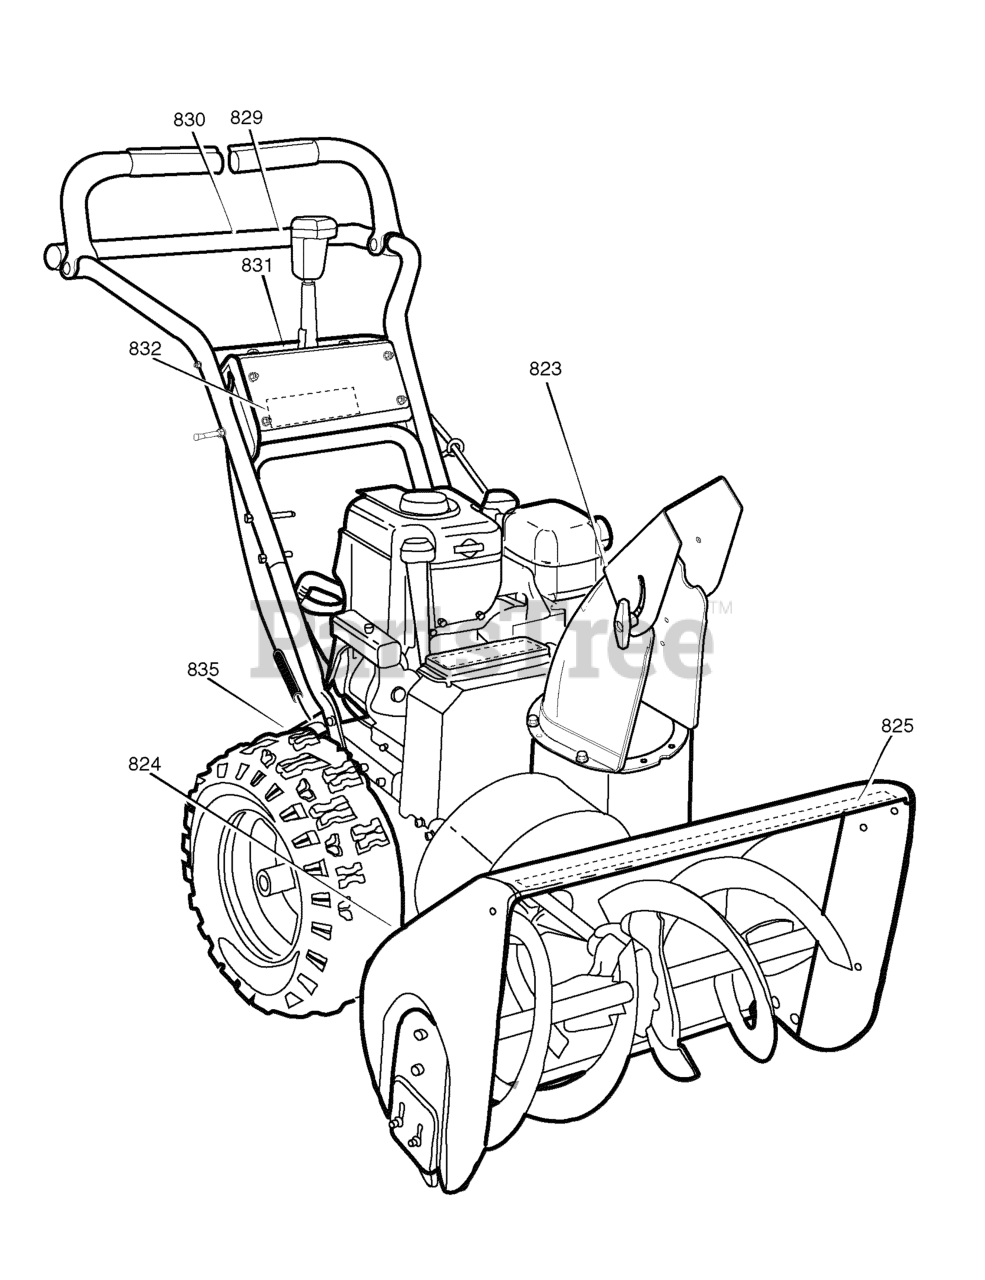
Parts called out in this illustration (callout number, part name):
823	DECAL, DANGER CHUTE HAND
824	DECAL, DANGER FOOT
825	DECAL, CRAFTSMAN 1350/30
829	DECAL, Traction Control Symbols
830	DECAL, Auger Control Symbols
831	DECAL, Gear Selector
832	DECAL, CRAFTSMAN
835	DECAL, ID PLATE
